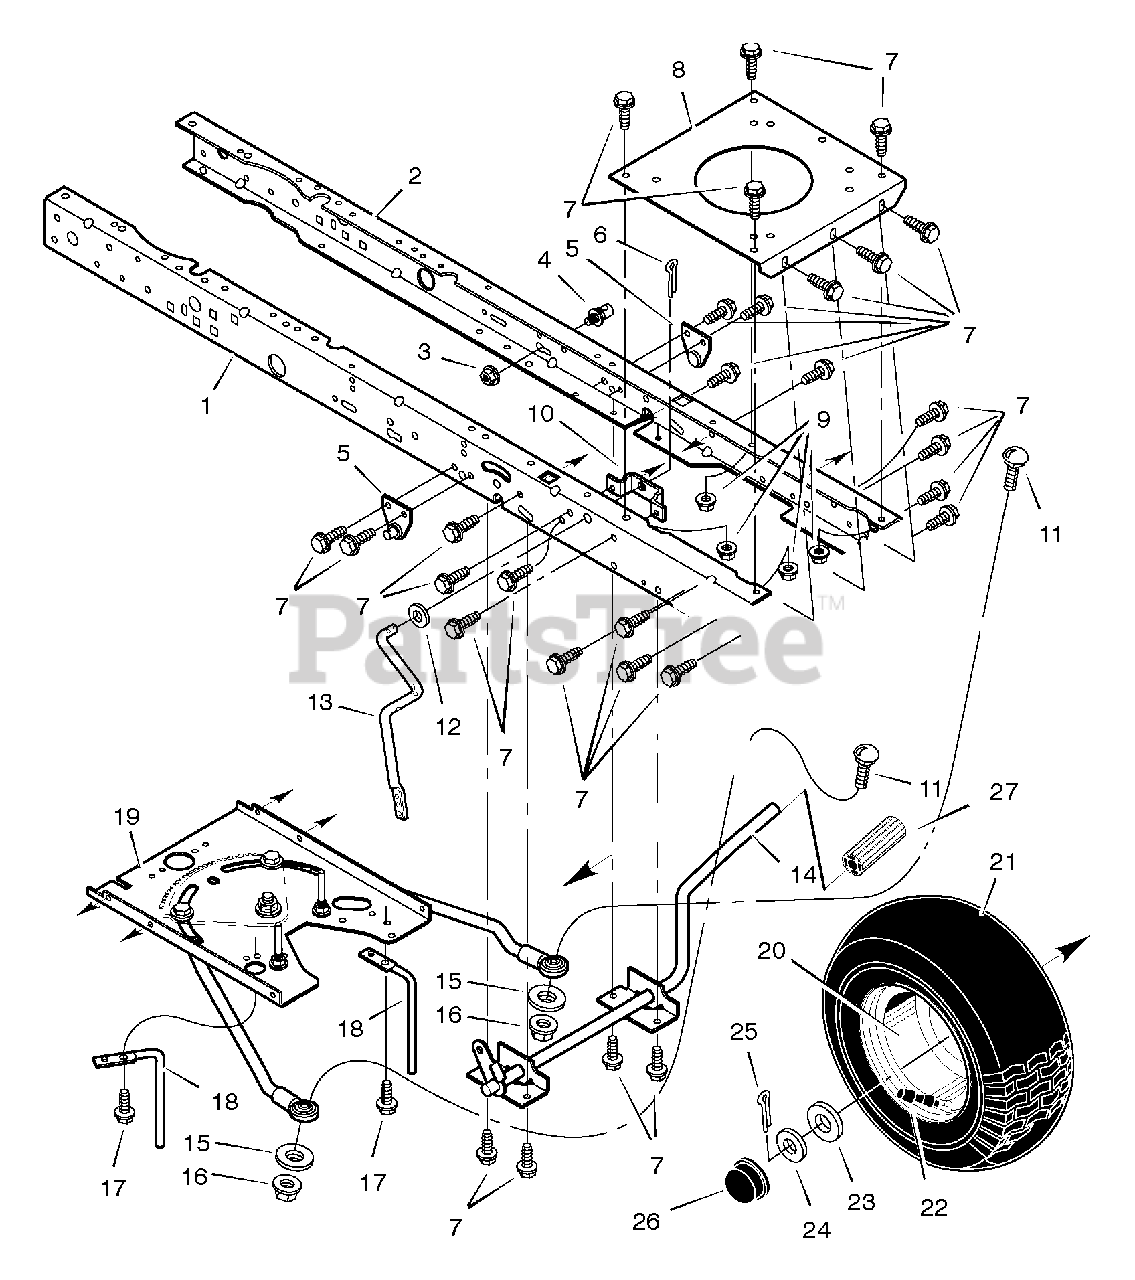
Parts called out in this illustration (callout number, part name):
1	Frame, Right
2	Frame, Left
3	Nut, Flange
4	Stud, Swivel
5	Bracket Ass'y, Suspension
6	Pin, Cotter
8	Plate, Engine
9	Nut
10	Bracket, PTO Crank
11	Bolt, Carriage
13	Crank, PTO
14	Lever, Brake/Clutch
15	Washer
17	Screw
18	Guide, Belt
19	Assembly, Steering *
20	Wheel & Tire Assembly
22	Stem, Valve
25	Pin, Cotter
26	Cap, Hub
27	Pedal
